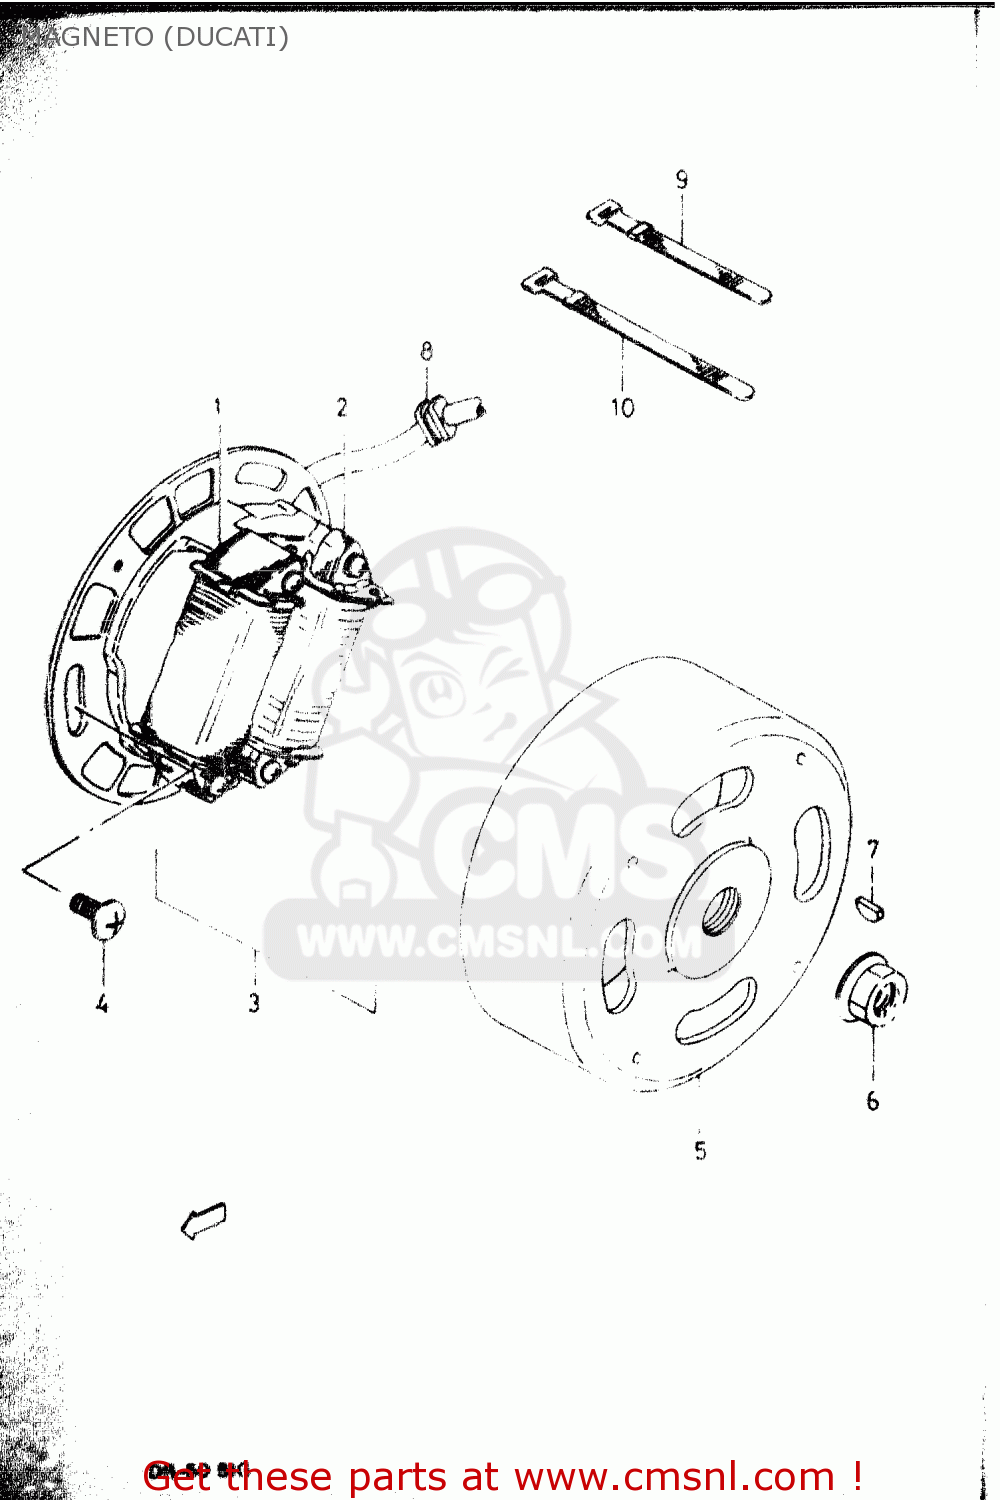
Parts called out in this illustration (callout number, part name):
1	COIL, LIGHTING
2	COIL, PRIMARY
3	STATOR ASSY
4	SCREW
5	ROTOR
6	NUT
7	KEY
8	CUSHION
9	CLAMP L=138
10	CLAMP L=170
